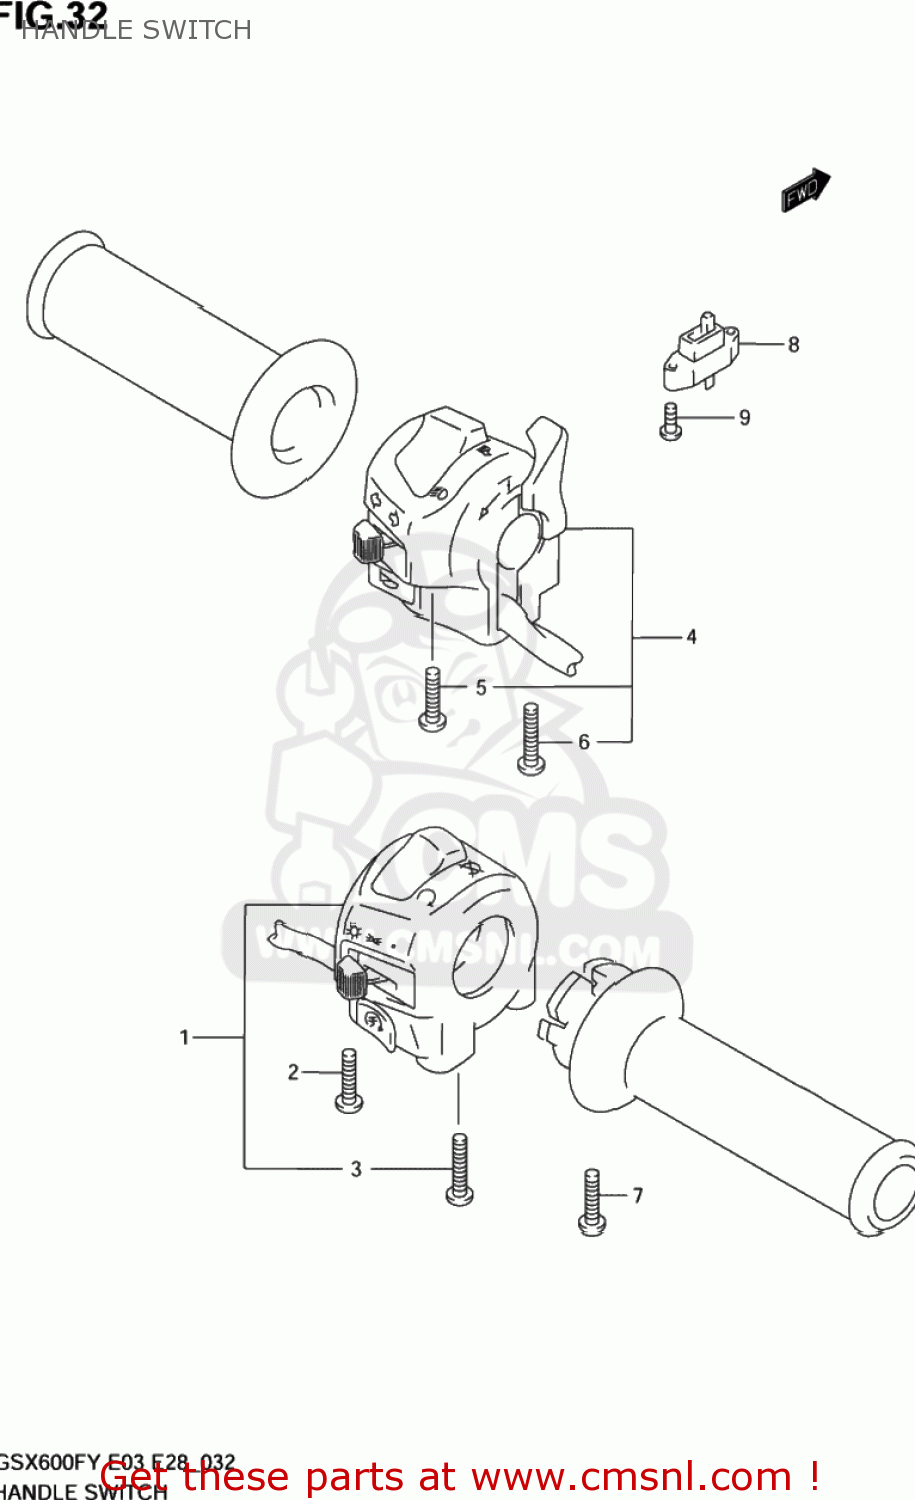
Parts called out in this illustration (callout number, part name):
1	SWITCH ASSY,HANDLE,R
2	SCREW
3	SCREW
4	SWITCH ASSY,HANDLE,L
5	SCREW
6	SCREW
7	SCREW
8	SWITCH ASSY,CLUTCH
9	SCREW
